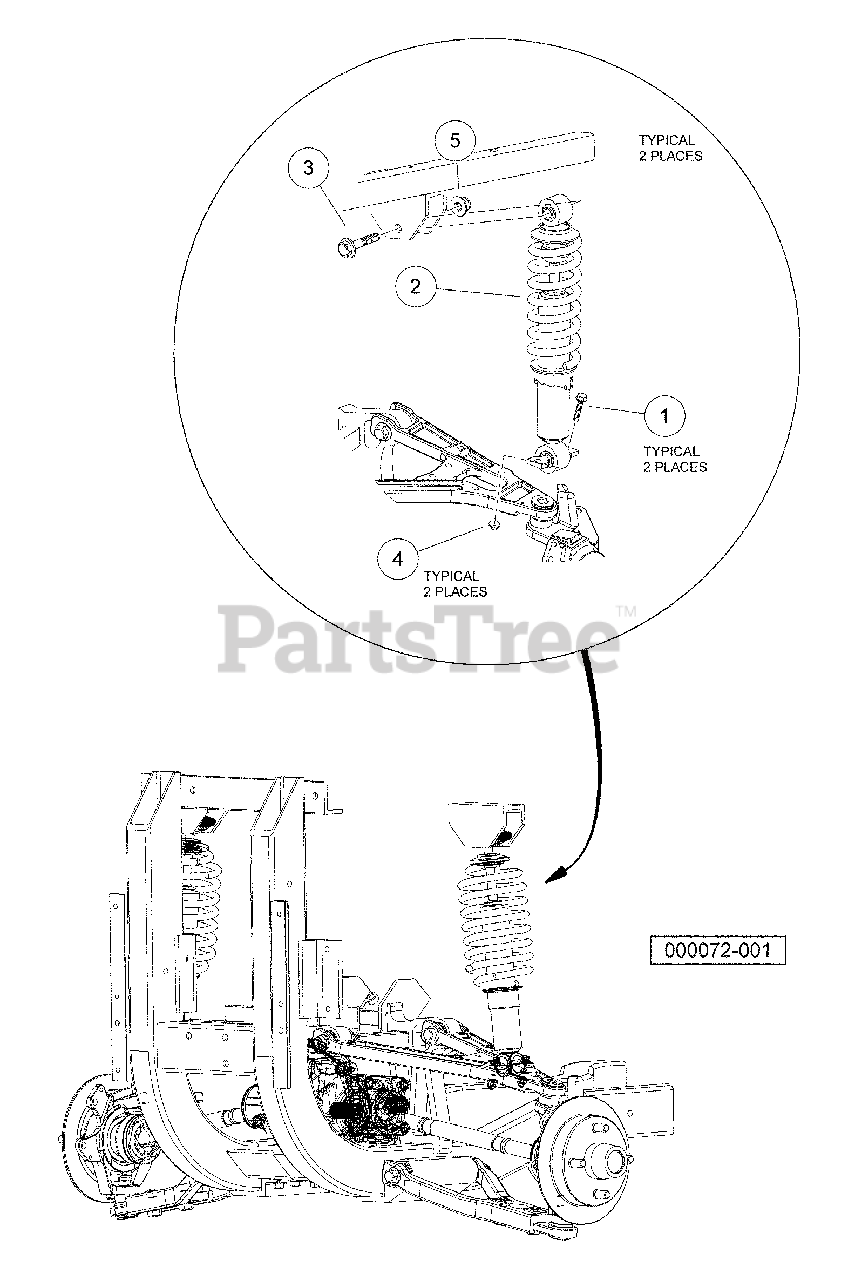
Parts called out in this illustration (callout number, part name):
1	Bolt, Flange Head, M8-1.25 X 40
2	Shock, Coil Over, Front Hd
3	Bolt, Flange Head, M12 X 1.75 X 70
4	Lock Nut, Flg M8 X 1.25 Nylon
5	Nut Flg, M12x1.75, Nylon Gr 10
